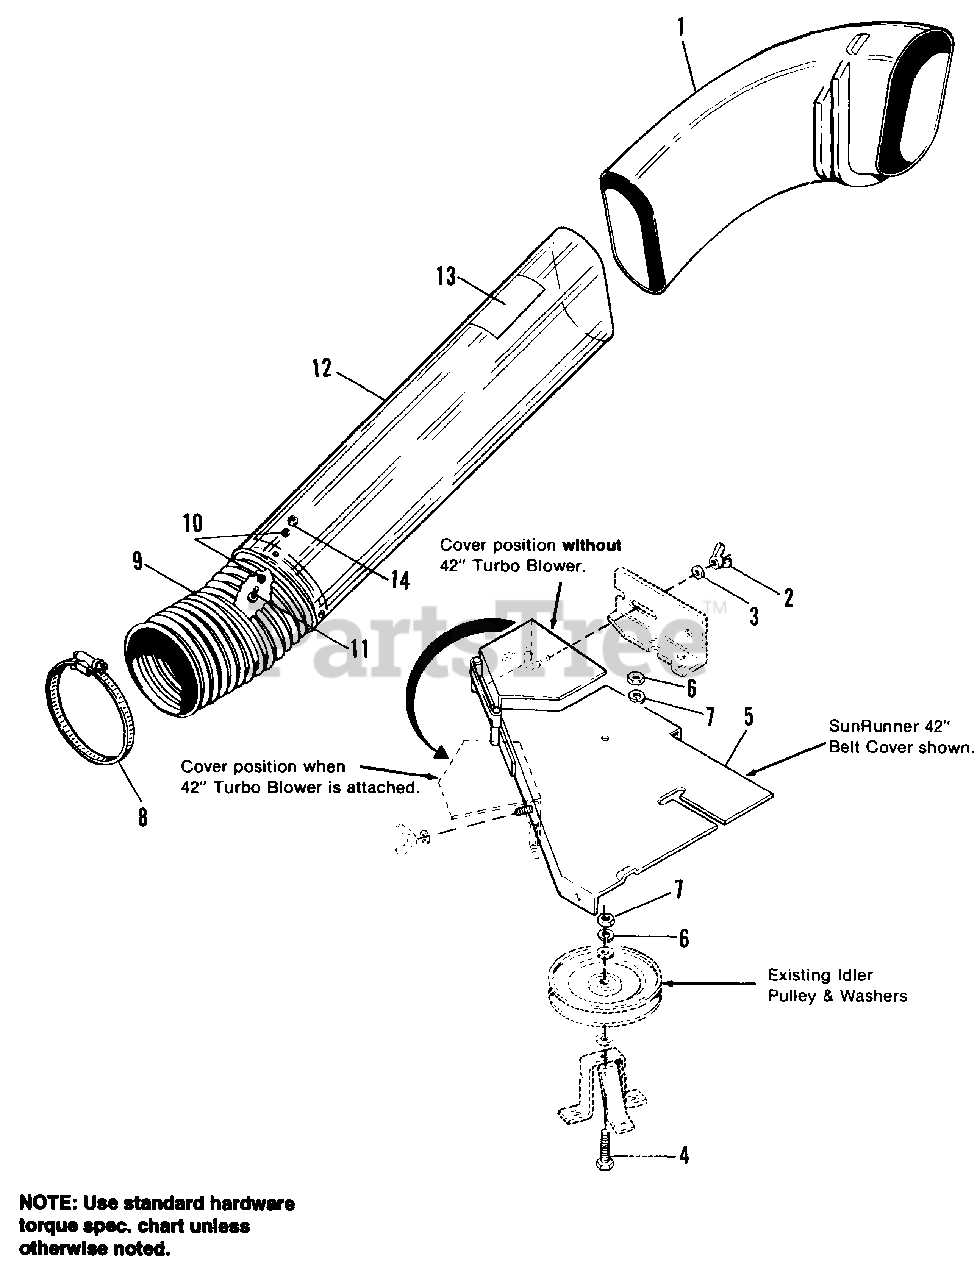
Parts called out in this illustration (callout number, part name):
2	WING NUT, 1/4-20
3	WASHER, 1/4
4	CAPSCREW, Hex Hd., 3/8-16 x 2 (SunRunner Only)
5	COVER ASSY., Belt (42" SunRunner Only)
5	COVER ASSY., Belt (42" FC Only)
6	NUT, Hex, 3/8-16
7	LOCKWASHER, 3/8
9	HOSE, Exhaust, 6" I.D.
10	WASHER, Rivet
11	SCREW, Truss Hd. Phil. #32 x 1/2
13	DECAL, Cleaning Inst.
14	NUT & WASHER ASSY., #10-32
